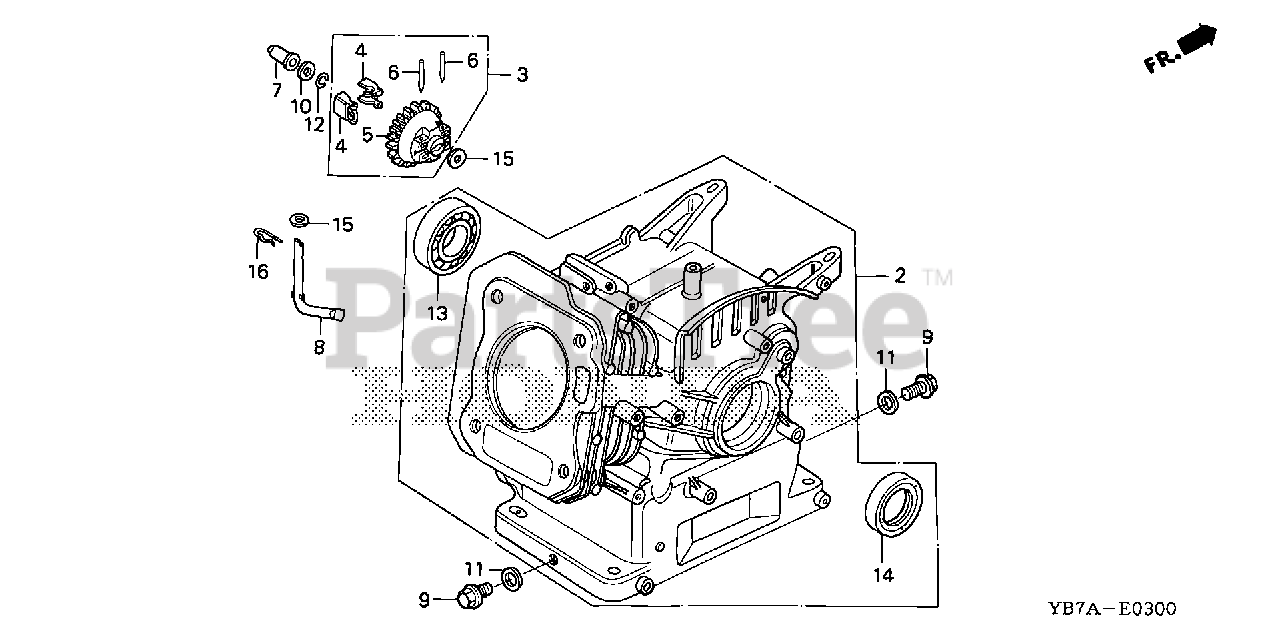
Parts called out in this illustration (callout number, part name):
2	CYLINDER ASSY. (STD) (NOT AVAILABLE)
3	GOVERNOR ASSY.
4	WEIGHT, GOVERNOR
5	HOLDER, GOVERNOR WEIGHT
6	PIN, GOVERNOR WEIGHT
7	SLIDER, GOVERNOR
8	SHAFT, GOVERNOR ARM
9	BOLT, DRAIN PLUG
10	WASHER, THRUST (6MM)
11	WASHER, DRAIN PLUG (10.2MM)
12	CLIP, GOVERNOR HOLDER
13	BEARING, RADIAL BALL (6205TMB) (NTN)
13	BEARING, RADIAL BALL (6205)
14	OIL SEAL (25X41X6) (NOK)
15	WASHER, PLAIN (6MM)
16	PIN, LOCK (8MM)
